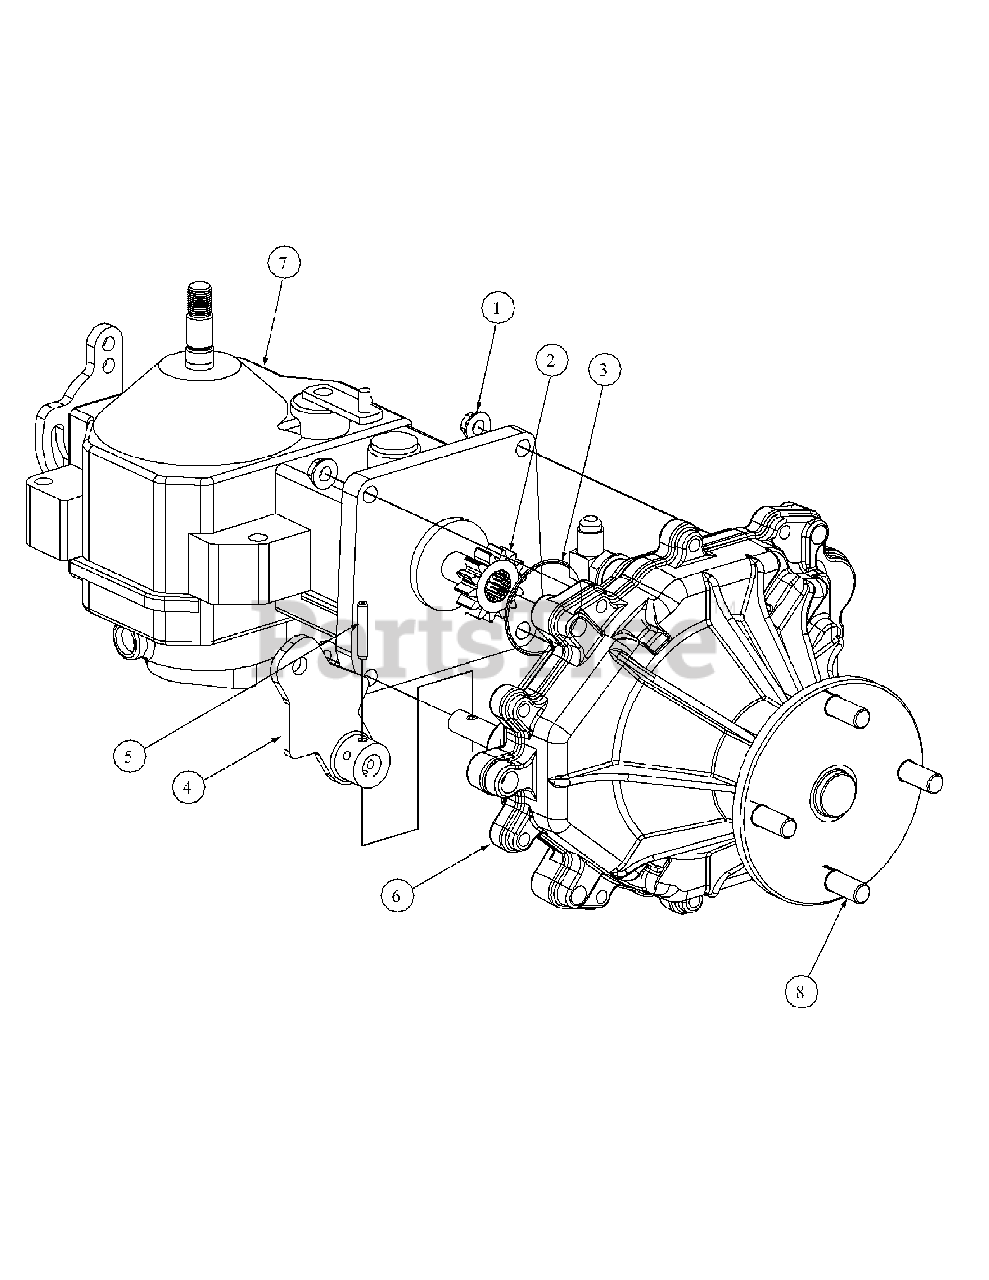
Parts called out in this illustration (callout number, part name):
1	Hex Flange, Lock Nut, 5/16-18
2	Gear, Spur, 14T
3	O-Ring, 2.00 x .070
4	Lever, Bracket, Park
5	Pin, Spirol, 3/16 x 1.25 HD
6	Transmission Assembly
8	Rib Neck Stud, 1/2-20
